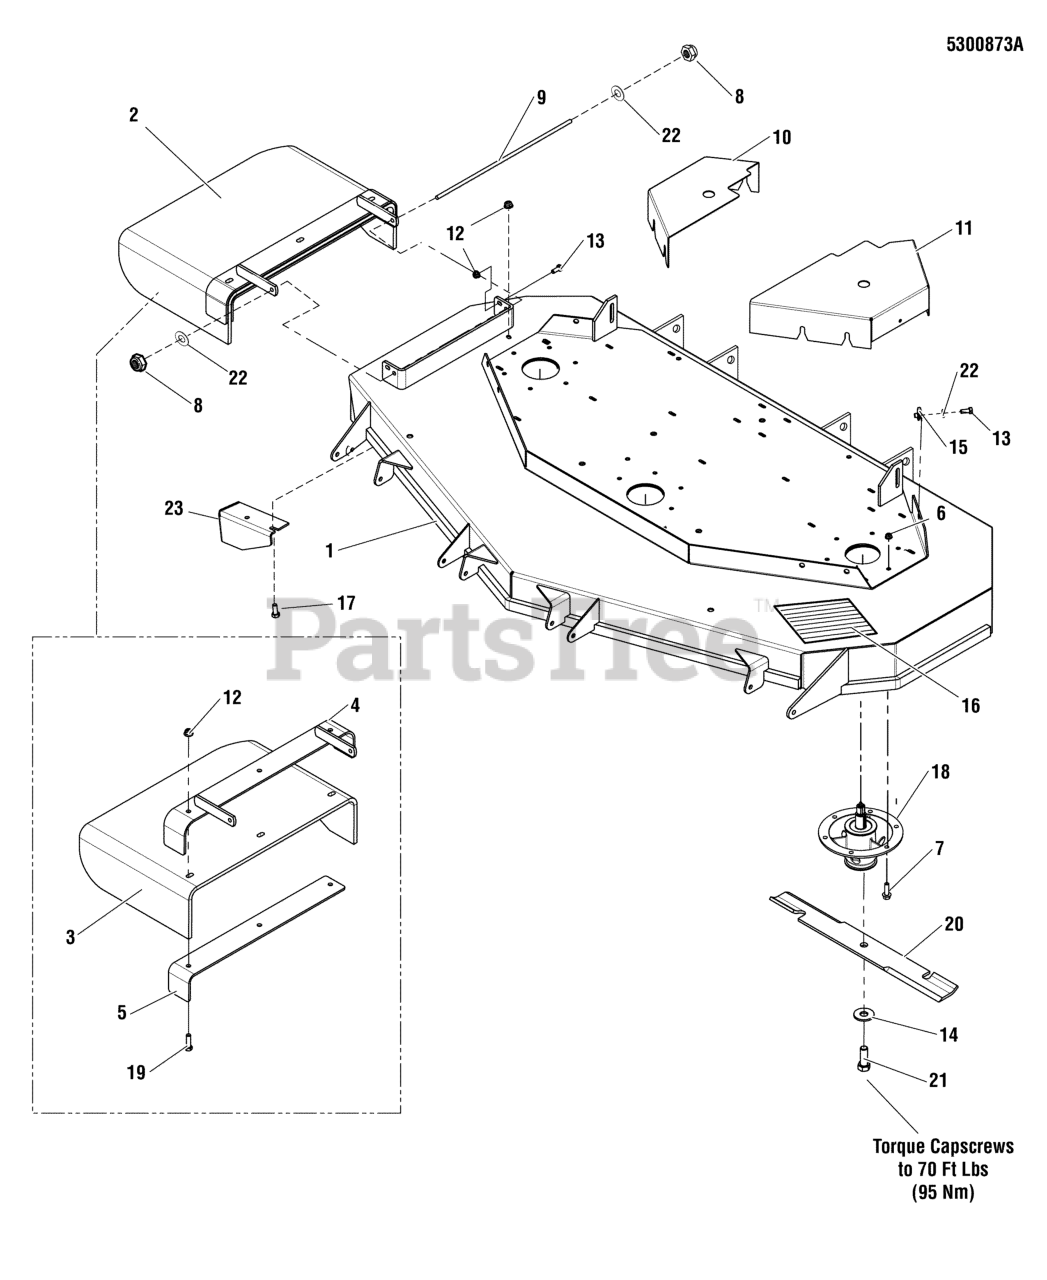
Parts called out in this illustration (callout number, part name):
1	DECK SHELL W/DECALS, 61" SIDE DISCHARGE
2	61" RUBBER CHUTE ASSEMBLY, Complete
3	CHUTE, DISCHARGE, RUBBER, 61/72"
4	WELD, FRAME, CHUTE, 61
5	SUPPORT, DISCHARGE CHUTE - BLK
6	NUT, 3/8-16 HEX NYLOCK FLANGE
7	BOLT, 3/8-16 X 1" GD5 CZ
8	NUT, 5/16-24 HEX NYLON LOCK
9	ROD MOUNT, CHUTE 61"
10	GUARD, 61", RH
11	GUARD, 61 - LH - RED
12	NUT, 5/16-18 HEX NYLOCK FLANGE
13	BOLT, 5/16-18 X 3/4 GD5
14	WASHER, 5/8" GRADE 8, YZ
15	BODY CLIP, 5/16-18-7GA MATERIAL
16	SAFETY WALK, 9.75 X 6.00
17	BOLT, 5/16-18 X 3/4, CARRIAGE
18	ASSM, SPINDLE, CAST IRON
19	BOLT, 3/8-16 X 1-1/2" GD5 CZ
20	BLADE SET, 61 DECK (SET OF 3 BLADES)
21	BOLT, 5/8-11 X 1-3/4" GD8
22	WASHER, 5/16" SAE
23	PLATE, DEFLECTOR - BLK
